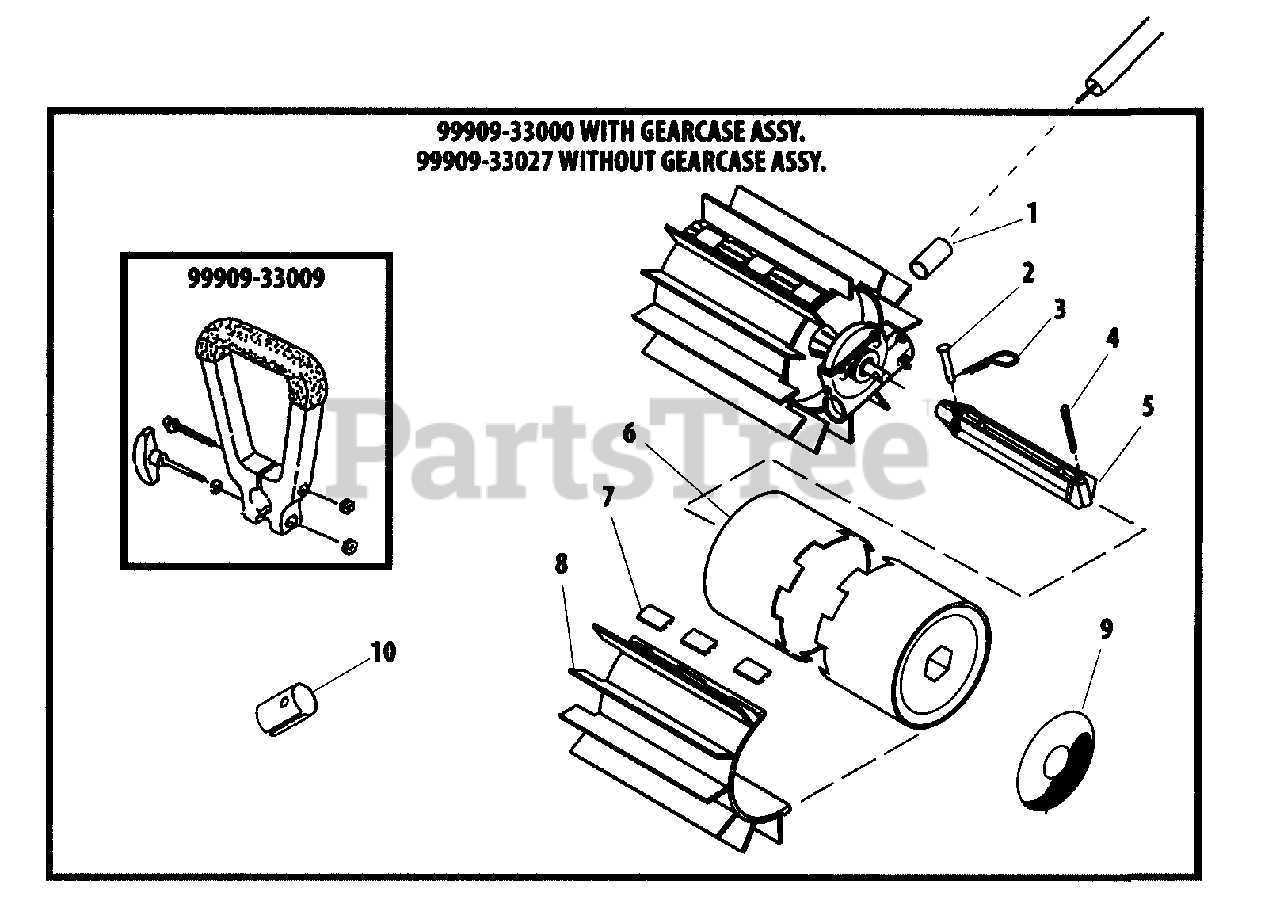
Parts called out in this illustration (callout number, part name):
1	CAP, MAIN PIPE
2	PIN - CLEVIS
3	PIN - HITCH
4	PIN, SPLIT
5	AXLE
6	HUB, DRUM
7	CLIP, BELT
8	BELT
10	SPACER
